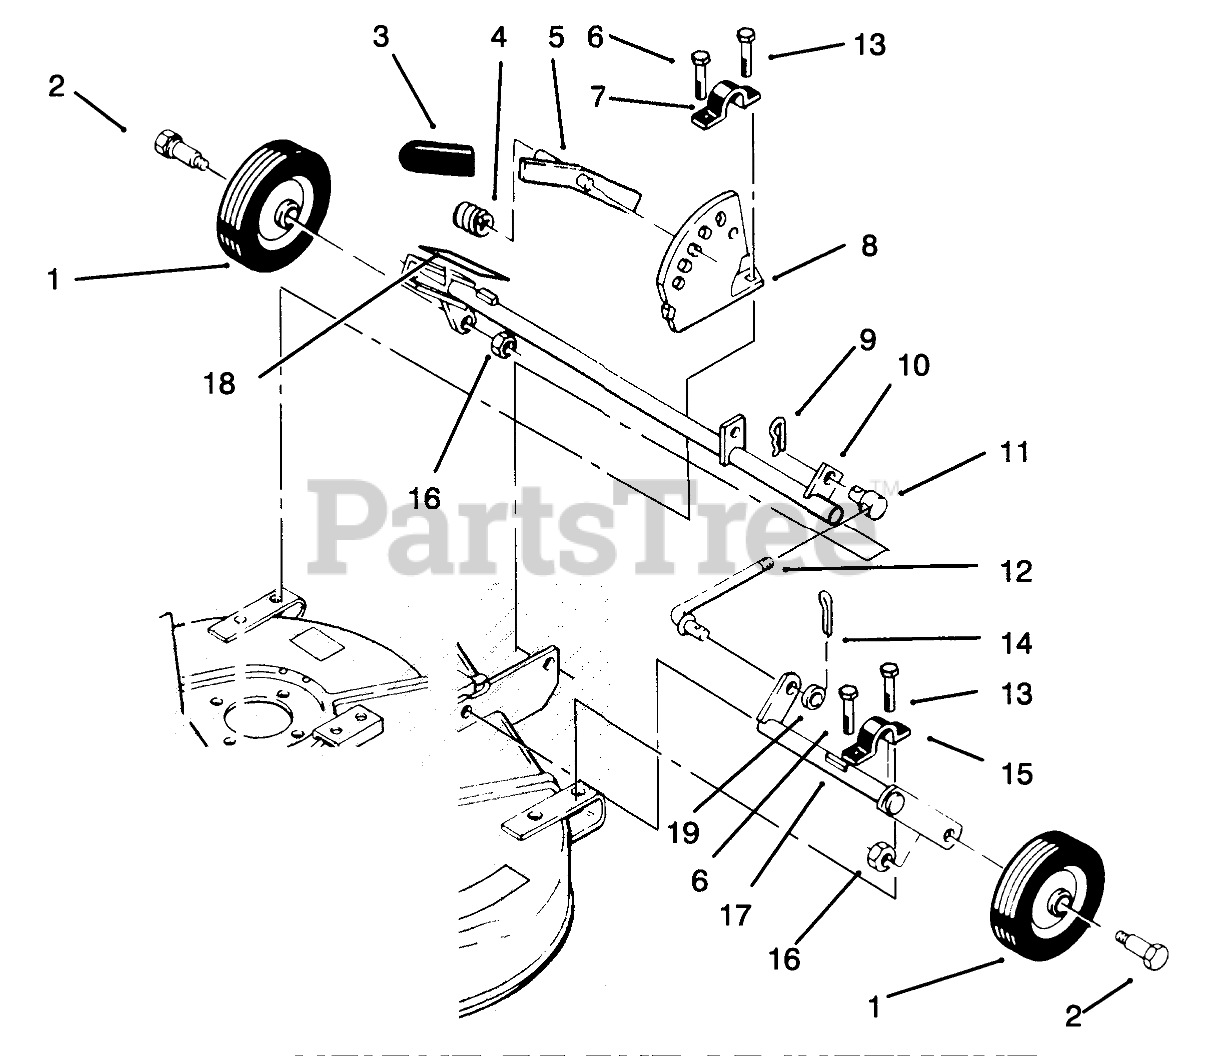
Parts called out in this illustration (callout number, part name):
1	WHEEL
2	BOLT-SHOULDER
4	SPRING-COMPRESSION
5	Lever
6	BOLT 3/8-16X7/8
8	Quadrant
9	PIN-HAIR
10	Gage Wheel Support RH
11	TRUNNION
12	ROD CONNECTING
13	SCREW-HWH, TAPTITE
14	PIN-COTTER
15	CLAMP B
16	NUT-LOCK, NI
17	WA GAG WHL R
18	DECAL-HOC
19	WASHER-FLAT
